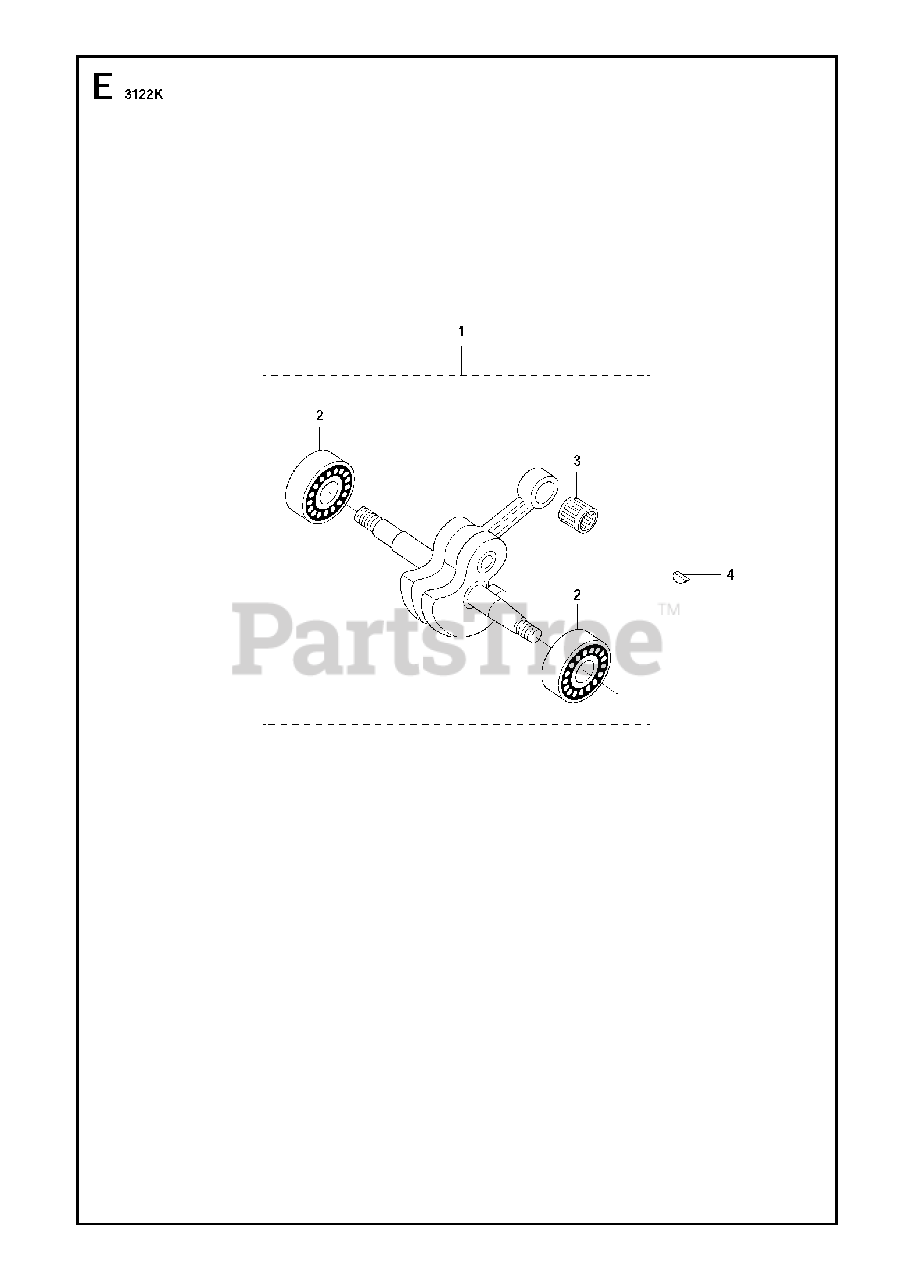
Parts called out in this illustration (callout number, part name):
1	CRANKSHAFTIncl. 2 - 3
2	BALL BEARING
3	NEEDLE HOLDER
4	WOODRUFF KEY
